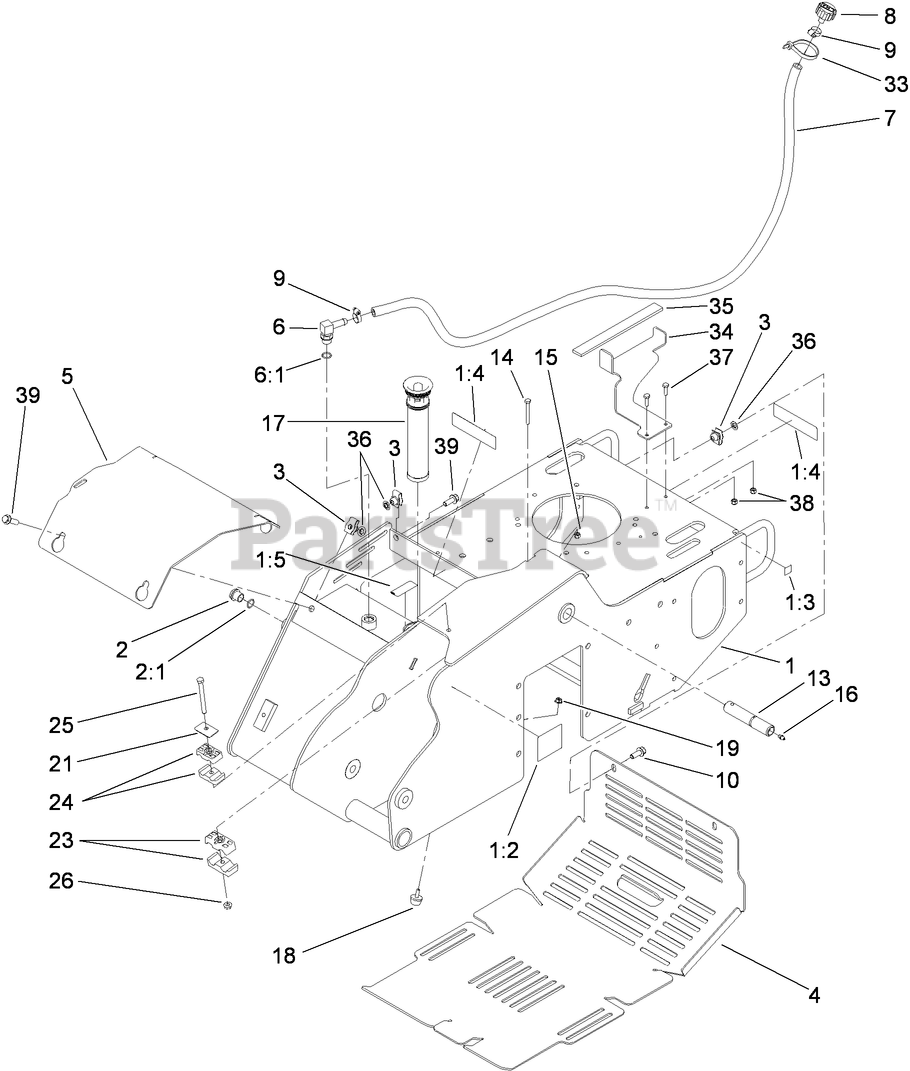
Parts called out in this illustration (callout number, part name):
1	MAIN FRAME ASM
1:2	DECAL-WARNING
1:3	DECAL-POINT, LIFT
1:4	DECAL-DANGER
1:5	DECAL-OIL, HYD
2	SIGHT GLASS ASM
2:1	O-RING
3	NUT-CLIP, U
4	COVER-REAR
5	PLATE-COVER, FRONT
6	FITTING-ELB 90
6:1	O-RING
7	HOSE-BREATHER
8	BREATHER
9	CLAMP-HOSE
10	SCREW-HHF
13	PIN-PIVOT
14	SCREW-HH
15	NUT-LOCK, NI
16	FITTING-GREASE
17	IN-TANK FILTER ASM
18	BUMPER
19	NUT-HF
21	COVERPLATE
23	CLAMP-TUBE
24	CLAMP-TUBE
25	SCREW-HH
26	NUT-HF
33	TIE-CABLE
34	BRACKET-TANK
35	PAD-FOAM
36	NUT-PUSH
37	SCREW-HH
38	NUT-LOCK, NI
39	SCREW-HHF
